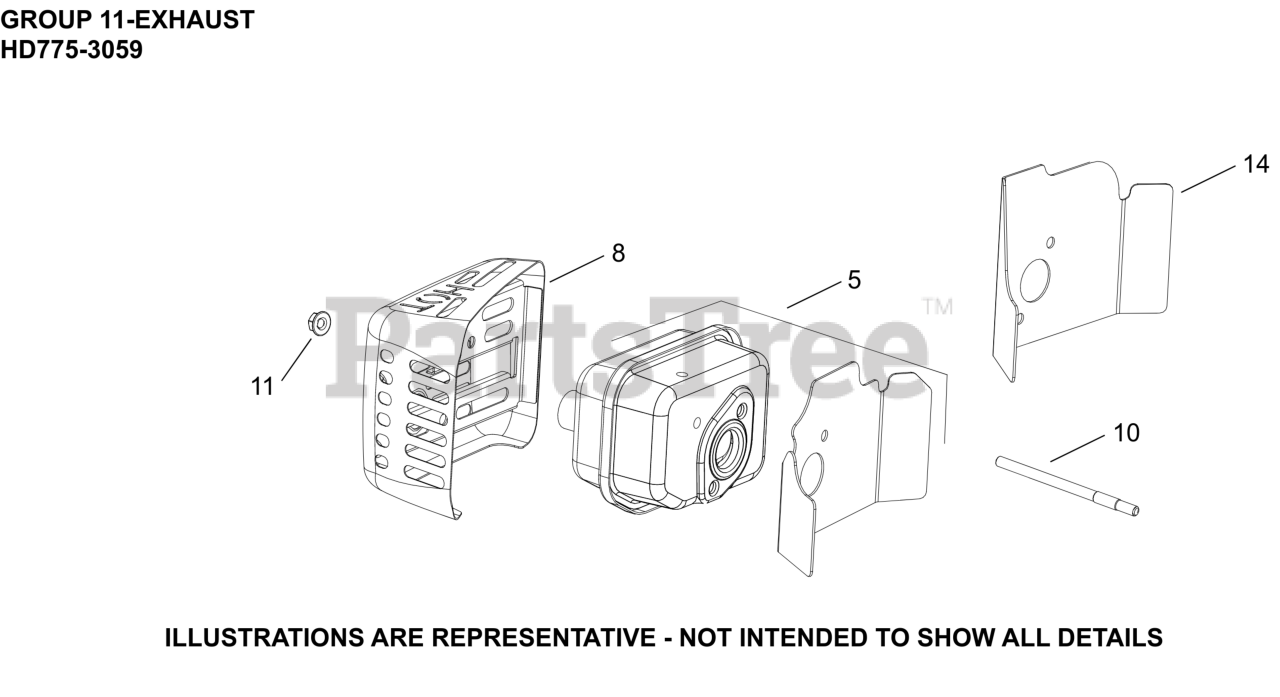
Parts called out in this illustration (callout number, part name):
5	KIT, MUFFLER
8	GUARD, MUFFLER
10	STUD, M6X1.0X93.8MM
11	NUT, HEX FLANGE LOCK (M6)
14	GASKET, MUFFLER (HEAT DEFLECTOR)
